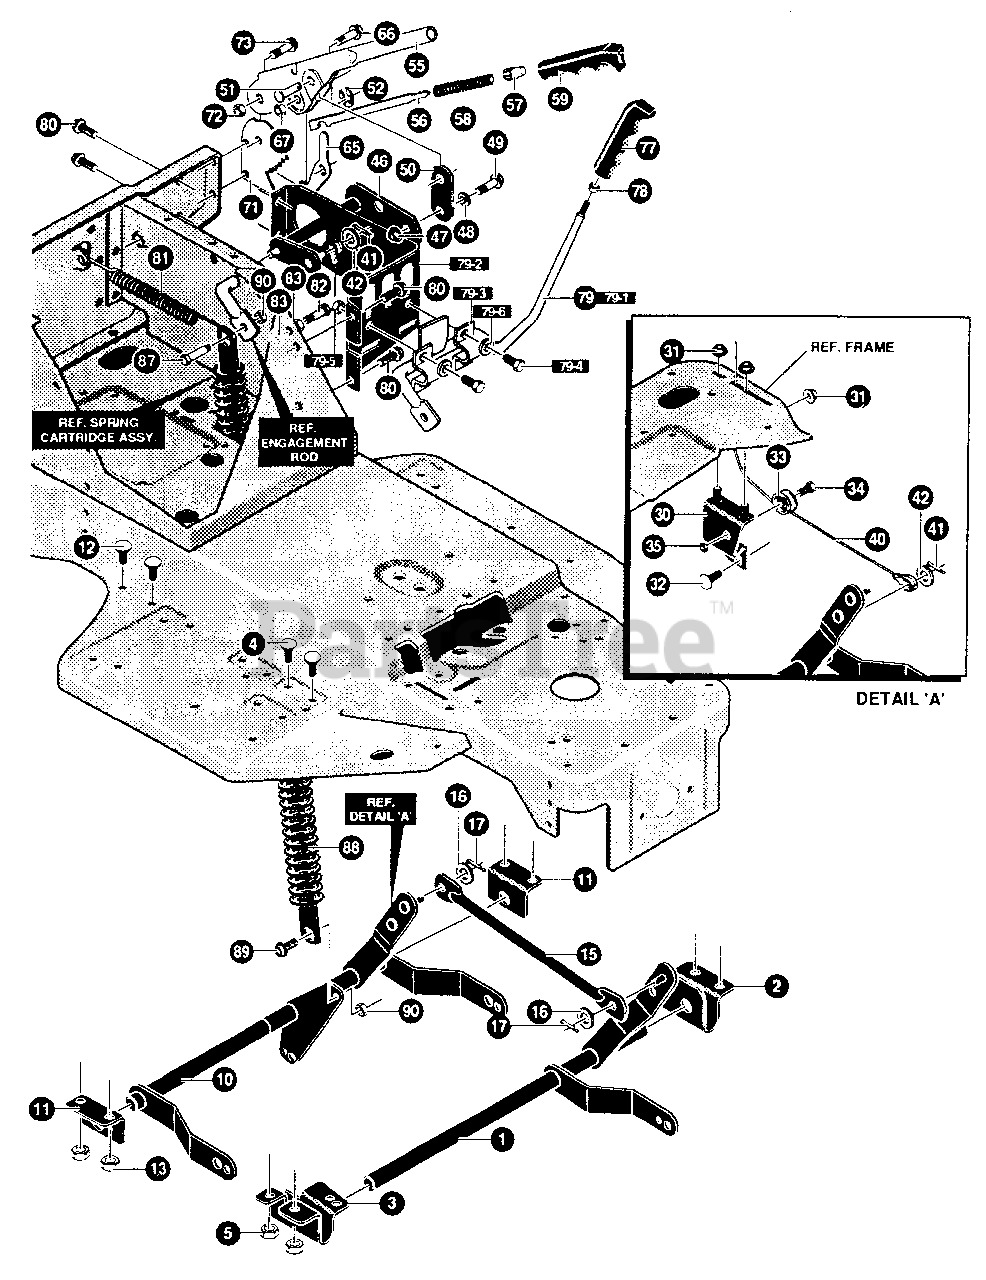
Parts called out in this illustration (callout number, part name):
1	SHAFT, ASSY FRONT LIFT EURO
2	BRACKET, FRONT HANGER RH
3	BRACKET, FRONT HANGER LH
4	SCREW, 5/16-18X .75 HHC
5	NUT, 5/16-18 REGHEXCTRLK
10	SHAFT, ASSY REAR LIFT
11	BRACKET, REAR HANGER EURO
12	SCREW, 5/16-18X .75 HHC
13	NUT. 5/16-18 REGHEXCTRLK
15	ROD, TIE
16	WASHER, FLAT .406X .81X.065
17	PIN, COTTER.090 DIAX.75LG
30	ASSY,PULLEY BRKT
31	NUT, 5/16-18 HXWDFLLK
32	BOLT. 5/16-18X 5/16-18X.63 CARR
33	PULLEY, POWDER METAL
34	BOLT, .375X .700 HHSH 5/16-18
35	NUT, 5/16-18 REGHEXCTRLK
40	CABLE, DECK LIFT
41	PIN, COTTER .090 DIAX.75LG
42	WASHER, FLAT .344X .69X.065
46	ASSY. UPPER SHAFT
47	NUT, 5/16-18 REGHEXCTRLK
48	WASHER, FLAT .333X .87X.1 19
49	BOLT, 375X .500 HHSH 5/16-18
51	PIN, CLEVIS .310DIA +.475LG
52	RING, RETE 31X.25TRUX5133-31
55	HEIGHT LEVER
56	ROD, ACTUATOR
57	KNOB, HEIGHT ADJ PUSH BUTTON
58	SPRING, HEIGHT ADJUST
59	GRIP, HAND .74IDX5.15
65	PAWL, SQUARE
66	BOLT-500X.270 HHSH 5/16-18
67	NUT, 5/16-18 HWDFLCTRLK
71	QUADRANT
72	NUT, 5/16-18 REGHEXCTRLK
73	BOLT. .500X .270 HHSH 5/16-18
77	HANDLE, 1/2-13
78	NUT, 1/2-13 HEXJAM
79	ASSY BRKT & ENGAGE HAND
79-1	ASSY. ENGAGEMENT ROD
79-2	BRACKET SUPPORT ENGAGE
79-4	SCREW, 1/4-20X .50 HHC
79-5	NUT, 1/4-20 REGHEXCTRLK
79-6	WASHER, FLAT .250X .56X.049
80	SCREW, 5/16-18X .50 WAHHTAP
81	SPRING, TENSION
82	SCREW, 3/8-16X2.50 HHC
83	NUT. 3/8-16 HEXKEPS
87	BOLT .437X.43 HHSH
88	ASSY. SPRING CARTRIDGE
89	BOLT, .437X .156 HHSH 5/16-18
90	NUT, 5/16-18 REGHEXCTRLK
